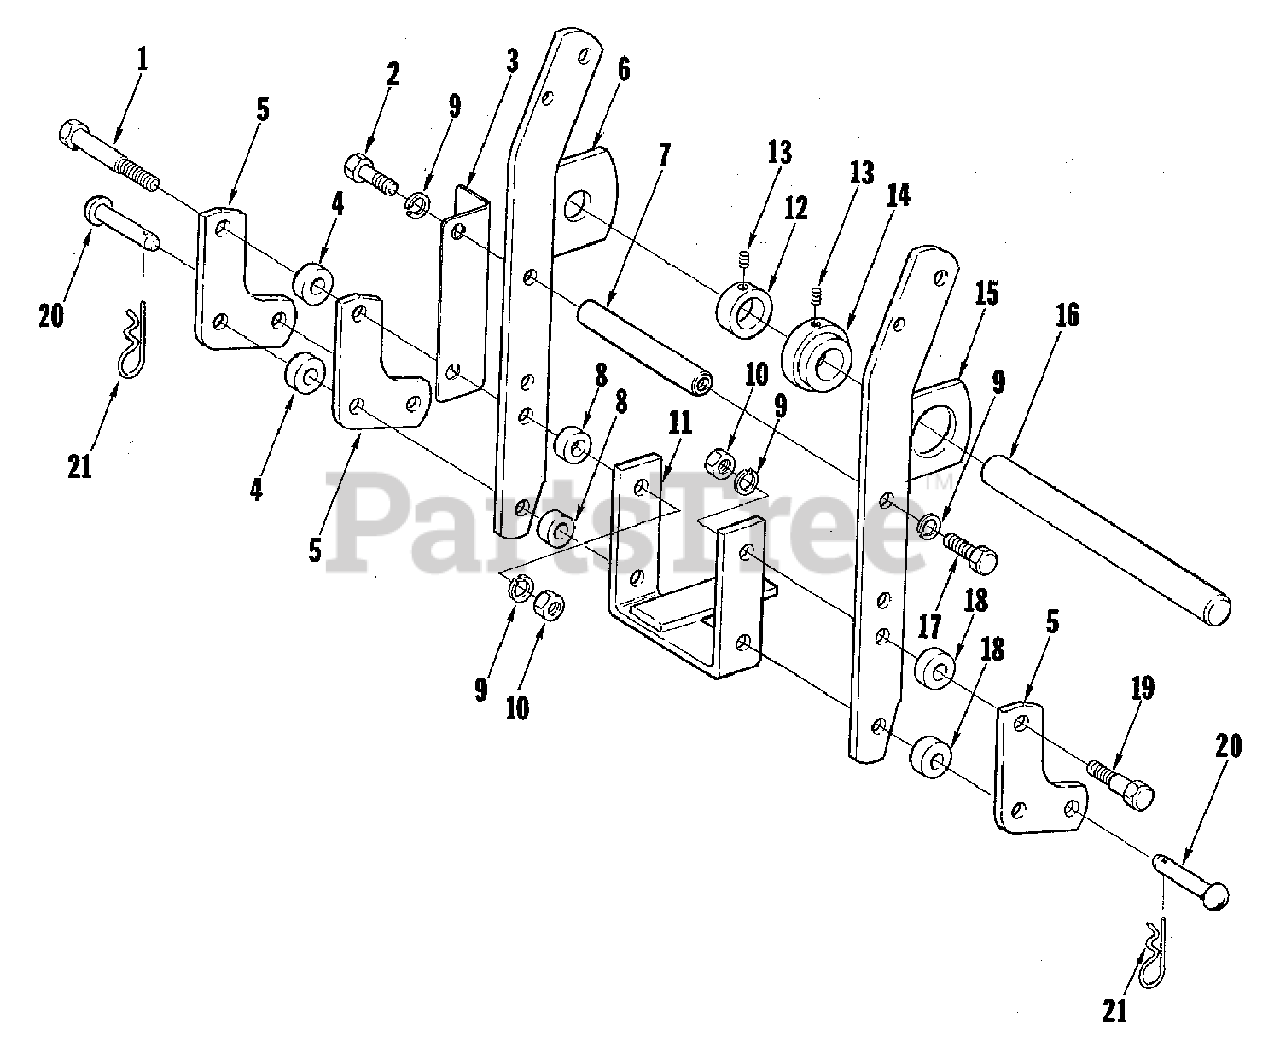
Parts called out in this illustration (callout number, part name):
1	SCREW, Hex Head Cap, 7/16-14 x 3
2	SCREW, Hex Head Cap, 7/16-14 x 1-3/4
3	PLATE, Decal
6	BAR ASSEMBLY, Upright
9	WASHER, Lock, 7/16
10	NUT, Hex Fin, 7/16-14
11	DRAWBAR ASSEMBLY
13	SCREW, Set, 5/16-18 x 5/16
15	BAR ASSEMBLY, Upright
17	SCREW, Hex Head Cap, 5/16-14 x 1-1/4
19	SCREW, Hex Head Cap, 7/16-14 x 2-1/4
20	PIN, Round Head
21	CLIP, Spring
